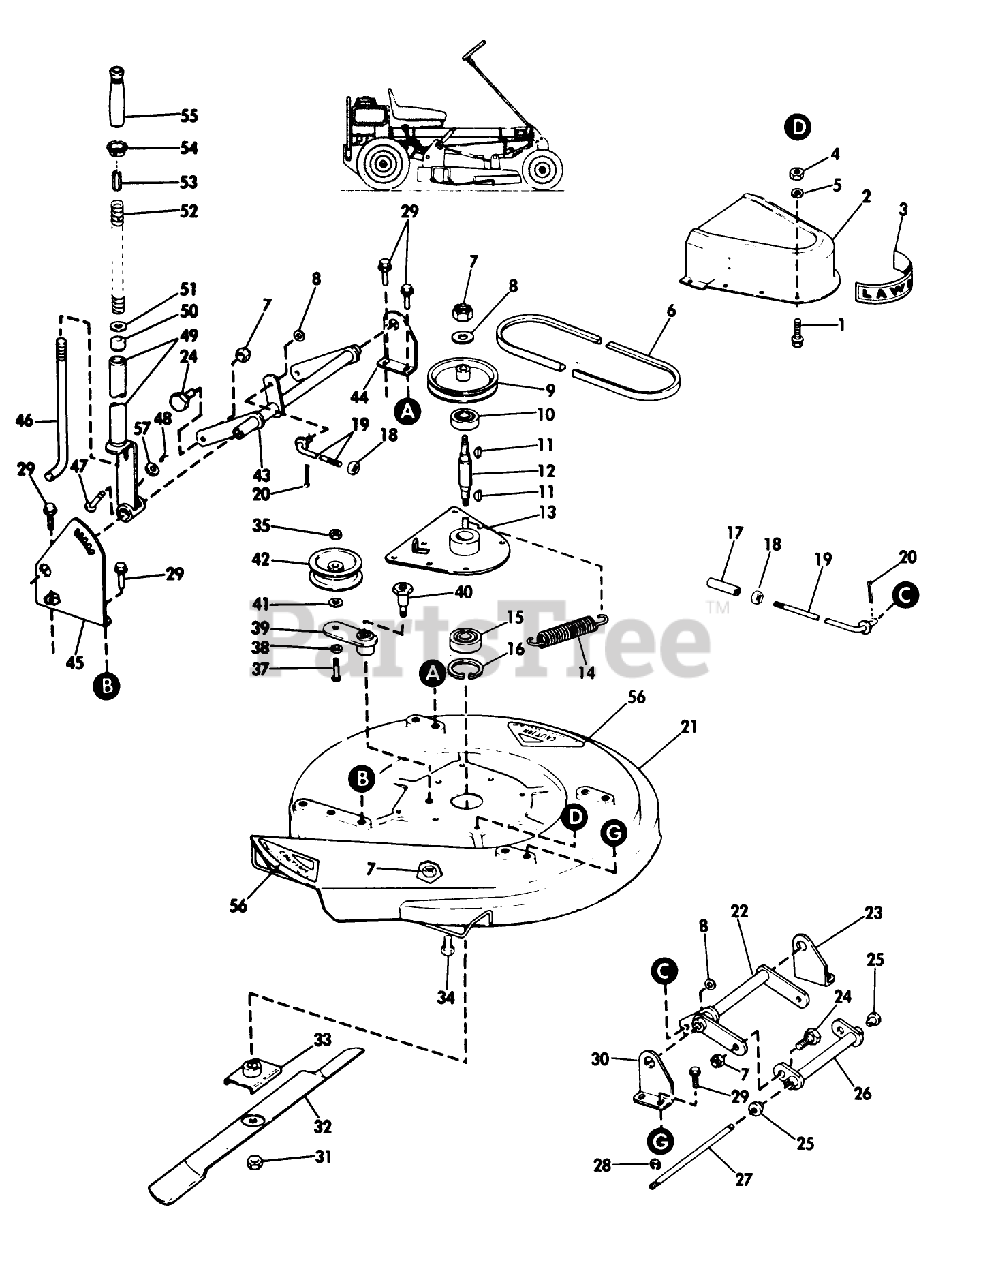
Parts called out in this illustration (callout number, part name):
4	Lockwasher
18	Jam Nut-Stabilizer Link Assembly
35	LOCKNUT
